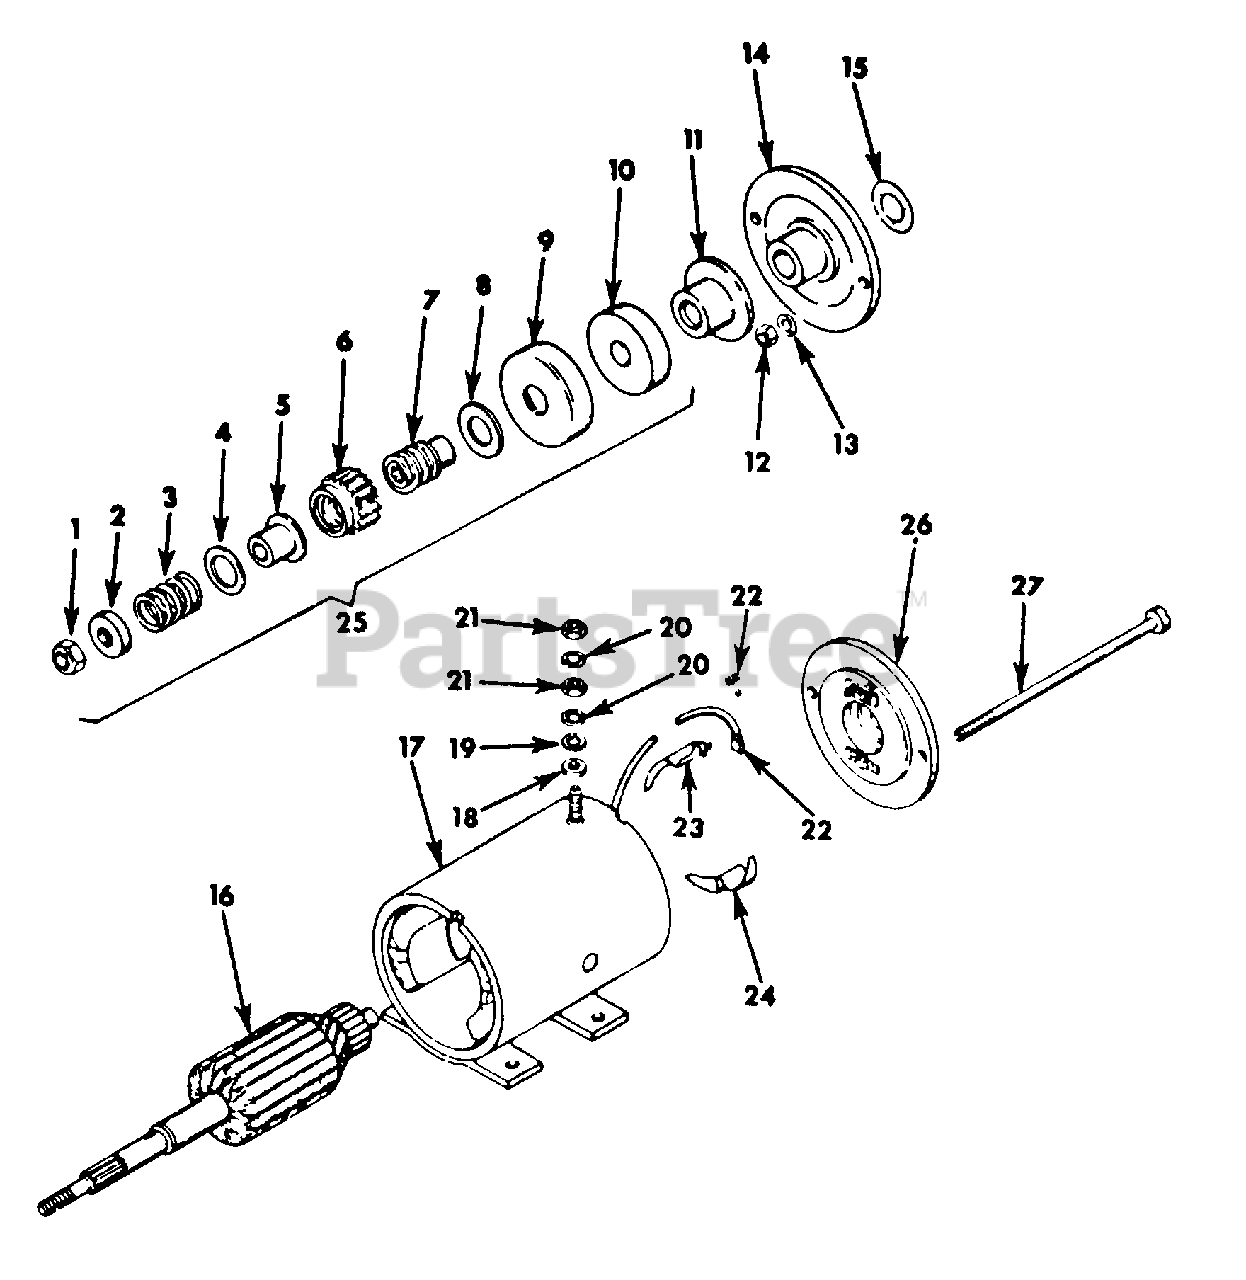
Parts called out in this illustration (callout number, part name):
1	NUT, ELASTIC STOP
2	STOP, PINION
3	SPRING, ANTI-DRIFT
4	WASHER, PINION
5	SLEEVE, ANTI-DRIFT
6	GEAR, PINION
7	SHAFT, SCREW
8	WASHER, THRUST
9	CUP, CUSHION
10	CUSHION, RUBBER
11	WASHER, THRUST
12	NUT, SECURING
13	WASHER, LOCK
14	CAP ASSY
16	ARMATURE
17	HOUSING ASSY
18	WASHER, INSULATING
19	WASHER
20	WASHER, LOCK
21	NUT, HEX.
22	BRUSH AND SPRING ASSY
23	INSULATION
24	INSULATION
25	DRIVE ASSY
26	CAP ASSY COMMUTATOR END
27	BOLT, THRU
